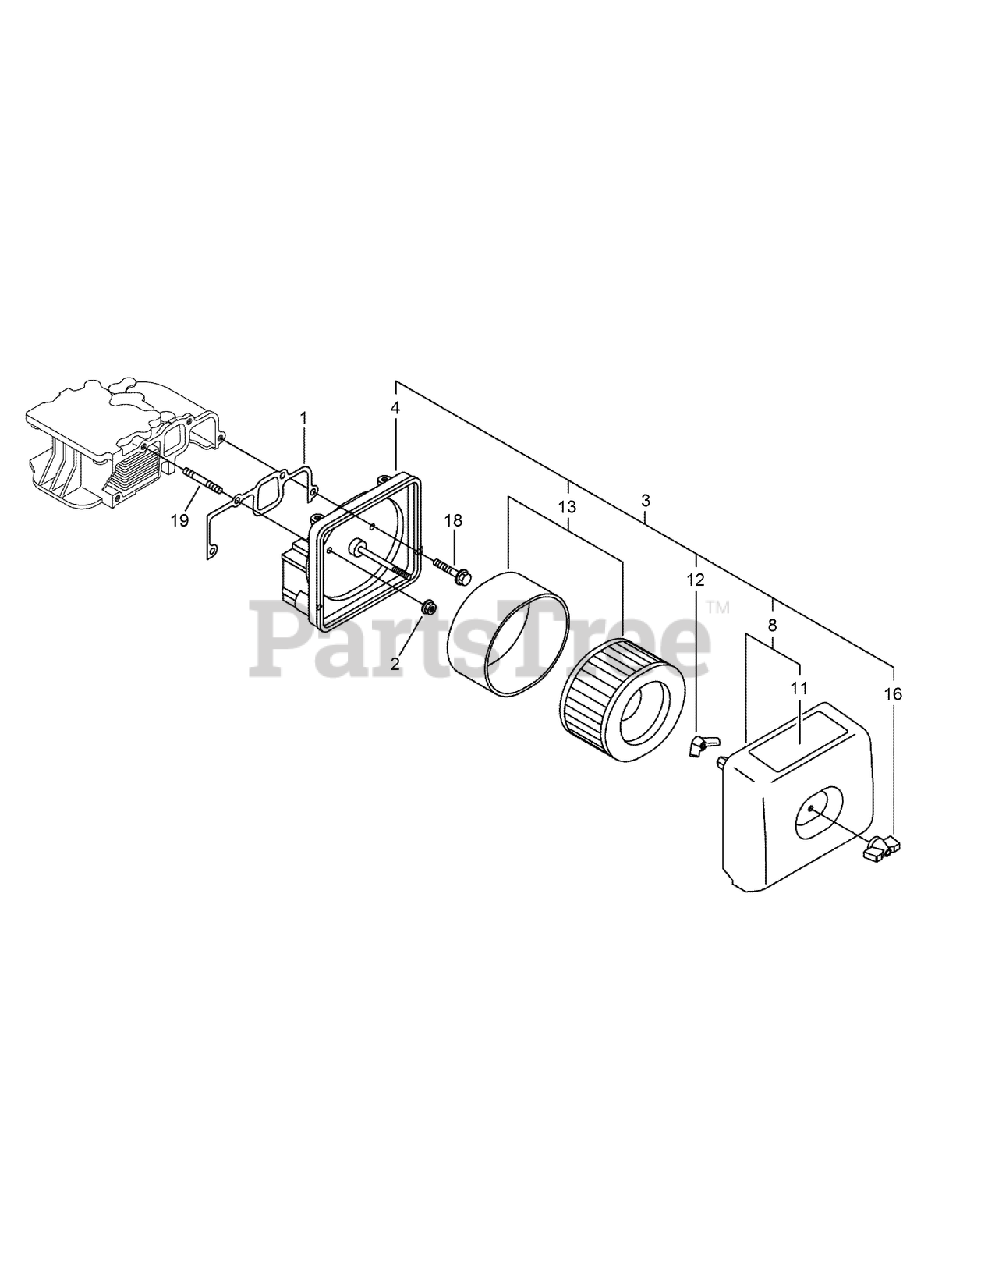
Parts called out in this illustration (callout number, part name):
1	GASKET-CLEANER, AIR
3	AIR CLEANER ASM
4	AIR CLEANER BODY ASM
8	AIR CLEANER COVER ASM
11	LABEL-CLEANER, AIR
12	NUT-WING
13	AIR ELEMENT ASM
16	KNOB-LOCKING
19	STUD-BOLT
